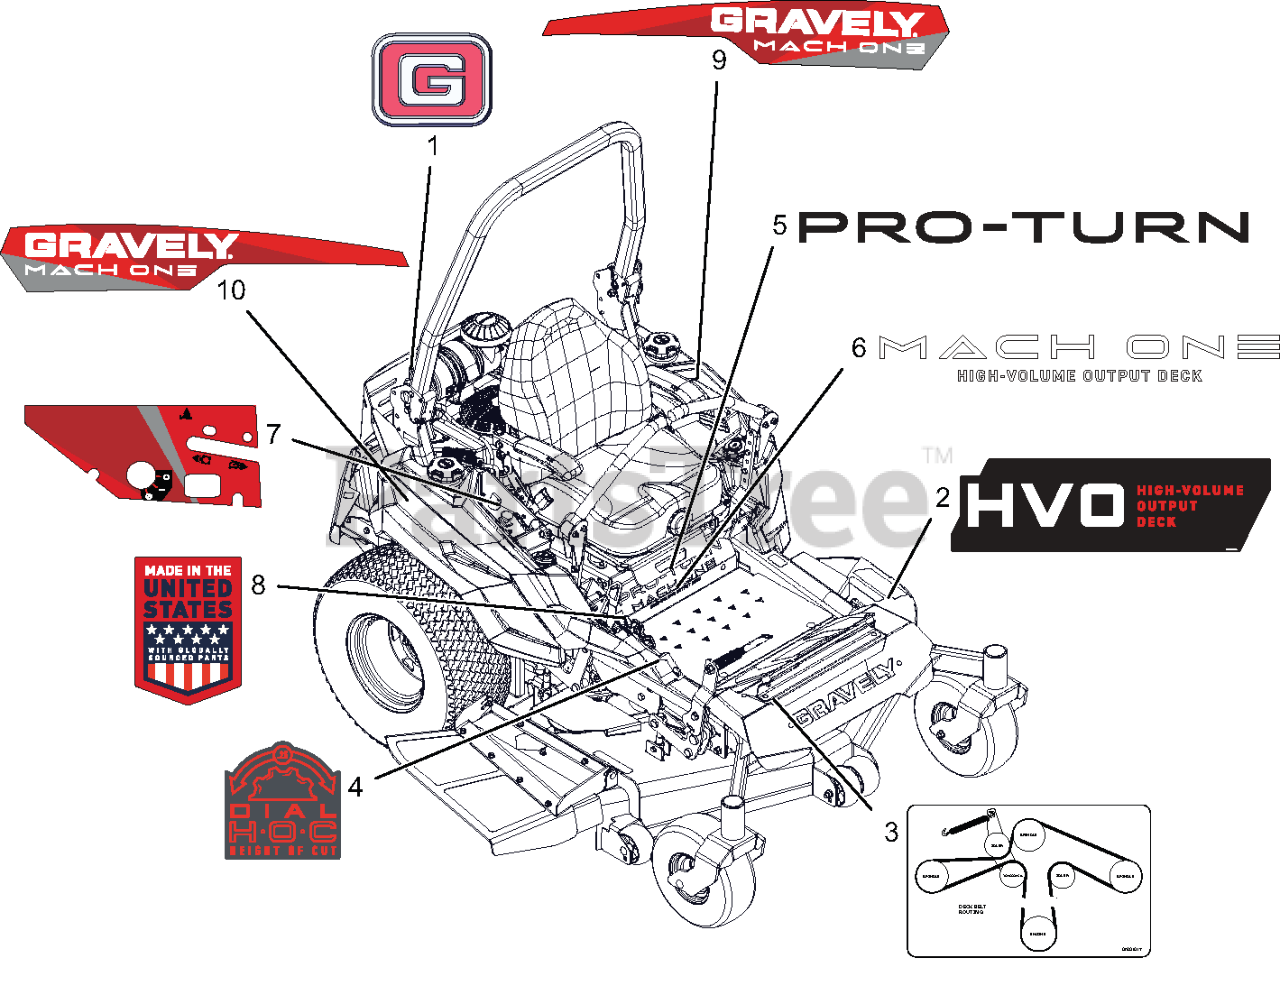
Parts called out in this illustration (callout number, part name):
1	DECAL, GRAVELY BRAND
2	DECAL, DECK - HVO
3	DECAL, BELT ROUTING
4	DECAL, COVER - HOC
5	DECAL, PRO TURN
6	DECAL MACH 1 (PT500)
7	DECAL- CONTROL PANEL
8	DECAL- MADE IN USA
9	DECAL- GRAVELY TANK - LH MACH1
10	DECAL- GRAVELY TANK - RH MACH1
